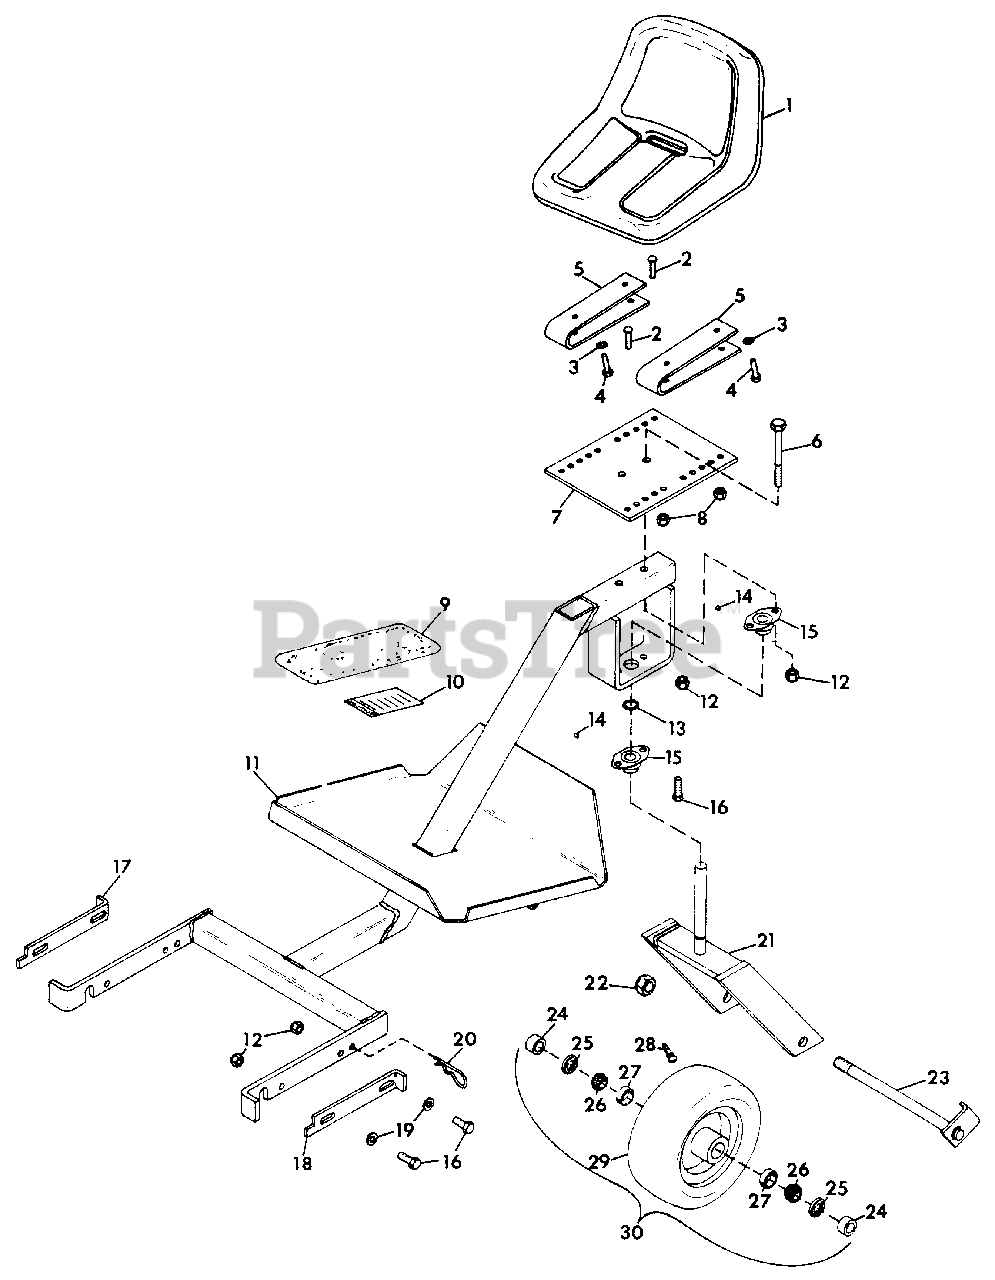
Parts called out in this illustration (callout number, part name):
1	SEAT, HIGH BACK
2	BOLT, 5/16-18X.875 RD HD SQ NK
3	WASHER, LOCK 5/16 REG.
4	BOLT, HEX 5/16-18X.75
5	SPRING, SEAT
6	BOLT, HEX 3/8-16X2.75
7	PLATE, SEAT SUPPORT
8	NUT, LOCK 5/16-18
9	COVER, LARGE FOOTBOARD
10	DECAL, SULKY PRO 40/PRO 50
11	WELDMENT, SULKY FRAME
12	NUT, LOCK 3/8-16
13	RING, RETAINING
14	SCREW, SET 1/4-28X.25
15	BEARING, FAN
16	BOLT, HEX 3/8-16X.75
17	STRAP, SULKY LATCH R.H.
18	STRAP, SULKY LATCH L.H.
19	WASHER, FLAT .375X1.125X.065
20	PIN, HAIR
21	WELDMENT, CASTER WHEEL FORK
22	NUT, LOCK 3/4-10
23	WELDMENT, AXLE
24	BUSHING, WHEEL
25	SEAL, WHEEL
26	BEARING, CONE
27	BEARING, CUP
28	ASSEMBLY, VALVE STEM
29	TIRE, 13X5.00-6
30	ASM., WHEEL 13X5.00-6
